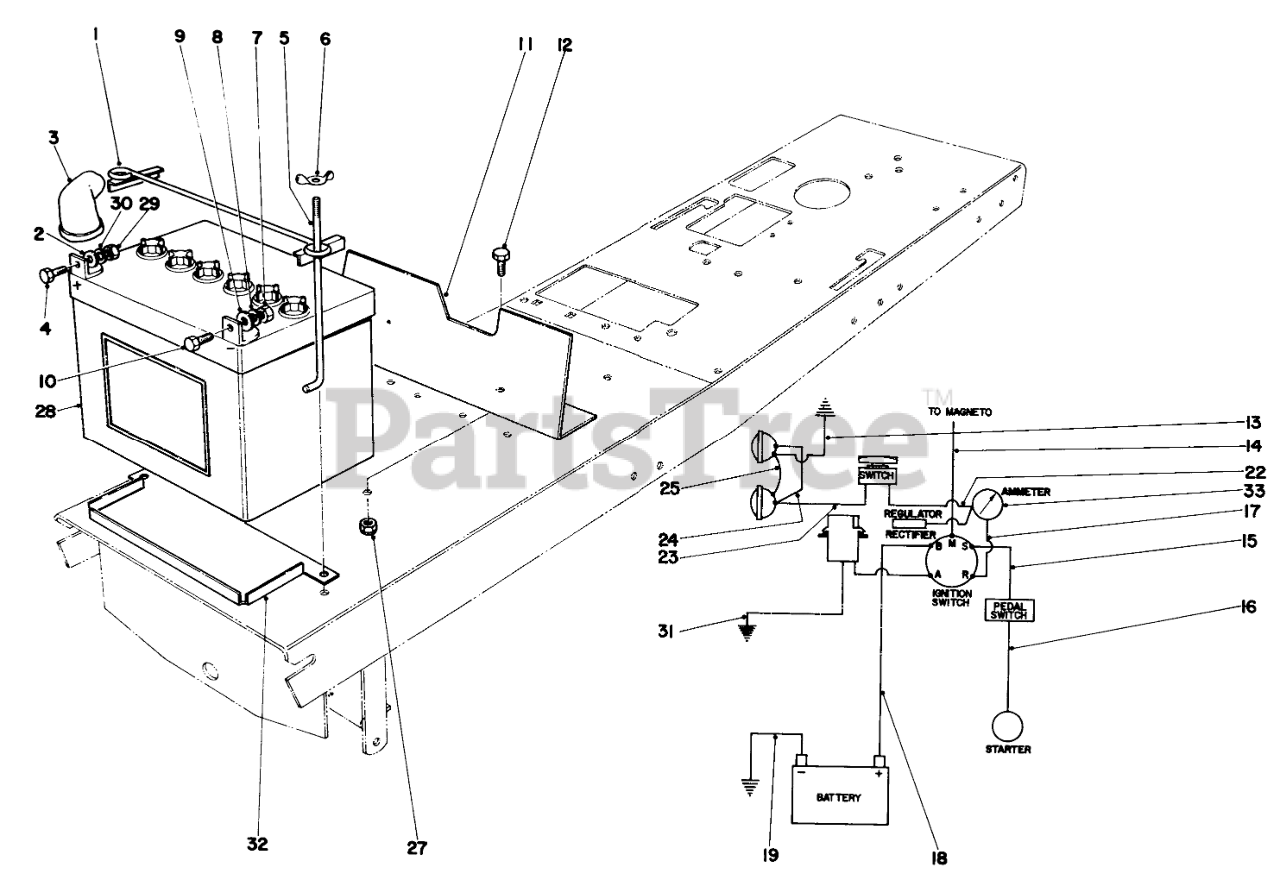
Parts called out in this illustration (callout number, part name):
1	Battery Clamp
2	Washer
3	Battery Boot
4	SCREW-HH
5	BATTERY BOLT
6	NUT-WING
7	NUT-HEX
8	WASHER-LOCK
9	WASHER-FLAT
10	SCREW-HH
11	Heat Shield
12	SCREW-HH
13	Wire Assy.-Red
14	Wire Switch to Battery
15	Wire Pedal Switch to Starter Switch
16	Wire Assembly
17	Wire Assy. Ammeter to Switch
18	Wire Assy. Switch to Battery
19	Wire Assembly
23	Wire Assy.
24	Wire 960
25	Wire 960
27	Nut
28	Battery
29	NUT-HEX
30	WASHER-LOCK
31	Wire Assembly
32	Retainer Battery
33	Ammeter
